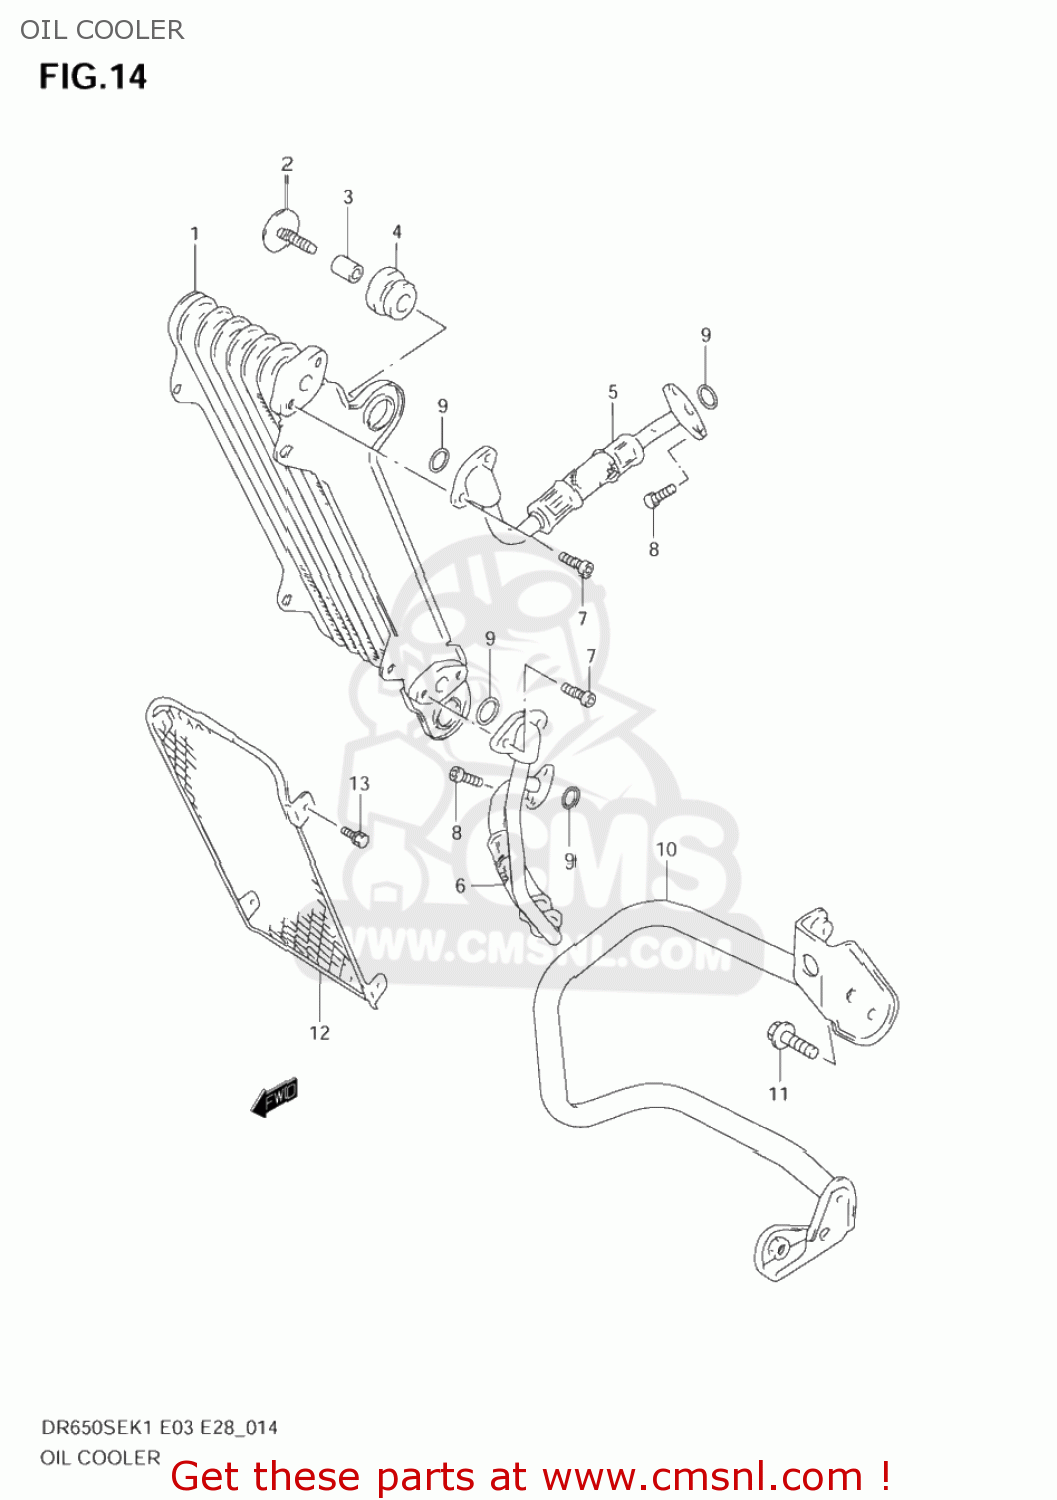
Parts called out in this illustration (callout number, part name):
1	COOLER ASSY,OIL
2	BOLT 8X28
3	SPACER(8.5X12X17)
4	CUSHION,OIL COOLER
5	HOSE,OIL COOLER UPR
6	HOSE,OIL COOLER LWR
7	BOLT,OIL FILLE
8	BOLT
9	O RING(D:2.4,ID:11.8)
10	GUARD,OIL COOLER
11	BOLT
12	BUMPER,OIL COOLER
13	BOLT
